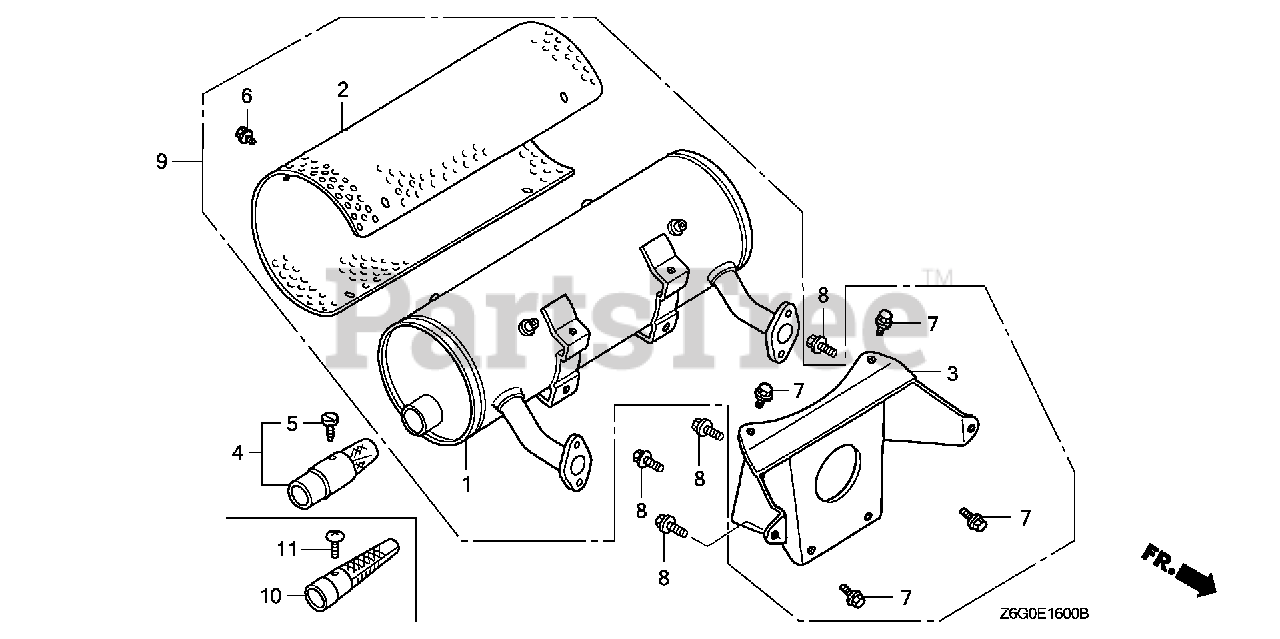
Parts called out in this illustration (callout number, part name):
1	MUFFLER COMP. (HIGH-R) (FUTABA) (SILVER MUFFLER) (FOR SILVER MUFFLER)
1	MUFFLER COMP. (HIGH-R) (FUTABA) (SILVER MUFFLER)
1	MUFFLER COMP. (HIGH-R) (NELSON) (BLACK MUFFLER) (FOR BLACK MUFFLER) (SHIFT18300-ZJ1-880) (IF N/A - #18300-ZJ1-881 RT.)
2	PROTECTOR, MUFFLER (HIGH) (FUTABA)
2	PROTECTOR, MUFFLER (HIGH) (FUTABA) (FOR SILVER MUFFLER)
2	PROTECTOR, MUFFLER (HIGH)(NELSON) (FOR BLACK MUFFLER)
3	STAY, MUFFLER (HIGH-FUTABA) (FOR SILVER MUFFLER)
3	STAY, MUFFLER (HIGH-NELSON) (FOR BLACK MUFFLER)
4	ARRESTER, SPARK (FOR BLACK MUFFLER)
5	SCREW (NELSON) (FOR BLACK MUFFLER)
6	BOLT, FLANGE (6X8)
7	BOLT, FLANGE (8X14)
8	BOLT, FLANGE (8X20)
9	MUFFLER ASSY. (HIGH-R) (FUTABA) (SILVER MUFFLER)
10	ARRESTER, SPARK (FOR SILVER MUFFLER)
11	SCREW, TAPPING (5X8) (FOR SILVER MUFFLER)
